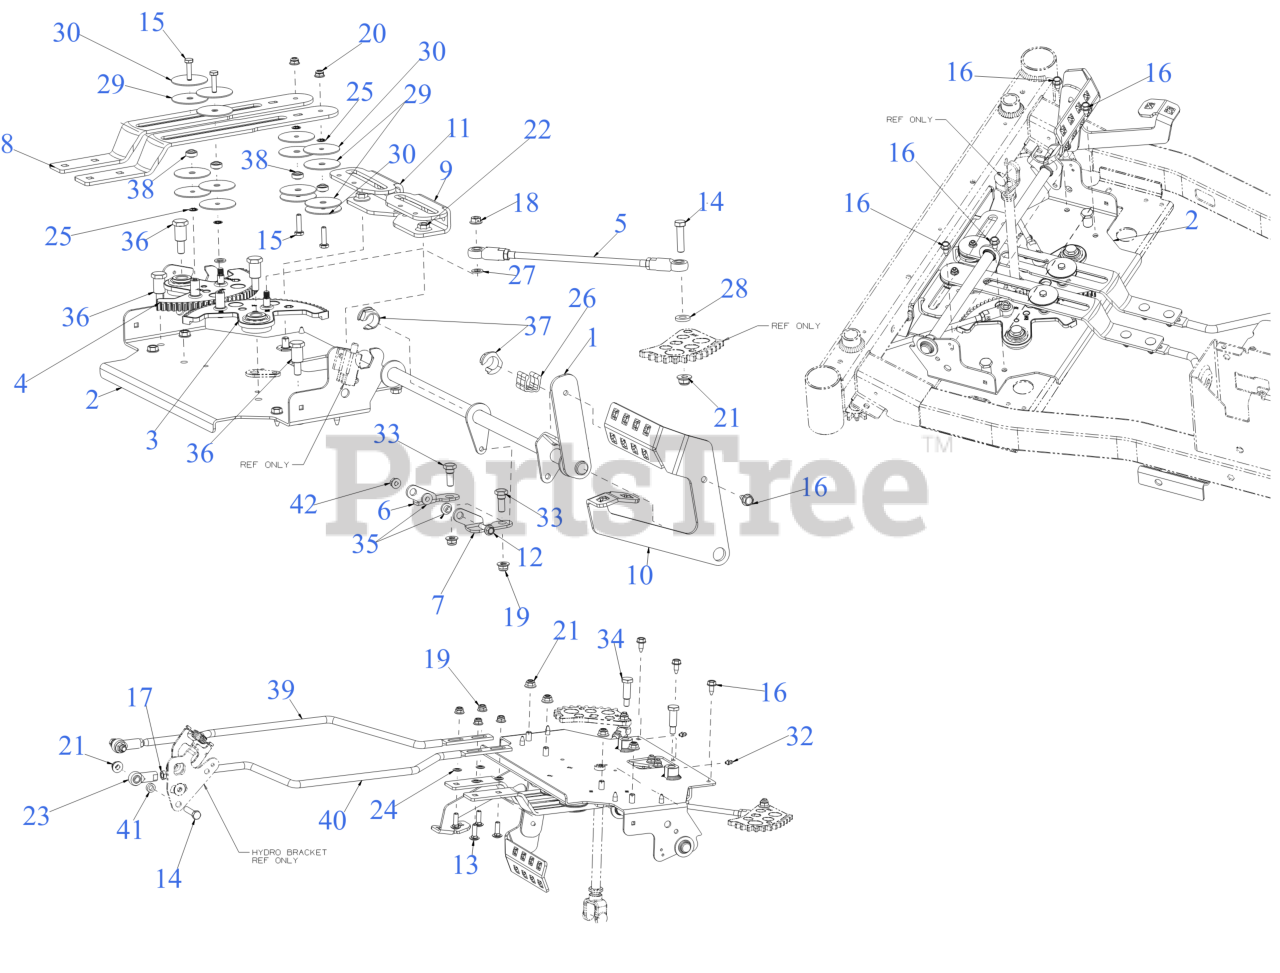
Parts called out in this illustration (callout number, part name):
2	STEERING SUPPORT PLATE
3	STEERING GEAR ASSEMBLY (RH)
3	FLANGE BUSHING
4	STEERING GEAR ASSEMBLY (LH)
4	FLANGE BUSHING
5	BALL JOINT
5	HEX JAM NUT 3/8X24
5	STEERING TIE ROD
6	PEDAL SHAFT BRACKET (LH)
7	PEDAL SHAFT BRACKET (RH)
8	CONTROL LINK
9	SPEED CAM PLATE (RH)
10	FWD/REV PEDAL
11	SPEED CAM PLATE (LH)
12	SCREW 1/4-20 x 1.0
13	CARRIAGE BOLT 5/16-18 x 1.00
14	SCREW 3/8-16 x 1.50
15	SCREW 1/4-20X1.0 GR5
16	SCREW 5/16-18 x .750
17	HEX JAM NUT 3/8X24
18	HEX FLANGE NUT
19	FLANGE LOCK NUT 5/16-18
20	FLANGE LOCK NUT
22	FLANGE LOCK NUT
23	BALL JOINT
25	RETAINER-BOLT .25ID x .50OD
26	SPACER-LIFT SHAFT
27	FLAT WASHER
28	FLAT WASHER
29	FLAT WASHER
30	FLAT WASHER
32	GREASE ZERT 1/4-28
33	SHOULDER SCREW .437
34	SHOULDER SCREW .50
35	SHOULDER SPACER
36	SHOULDER SCREW .625 x .875 x 3/18
37	HEX FLANGE SPLIT BEARING
38	BALL BEARING .25 x .625
39	HYDRO LINK ROD (RH)
40	HYDRO LINK ROD (LH)
41	SPACER-.380 ID x .625 OD x .227
42	LOCK NUT 1/4
